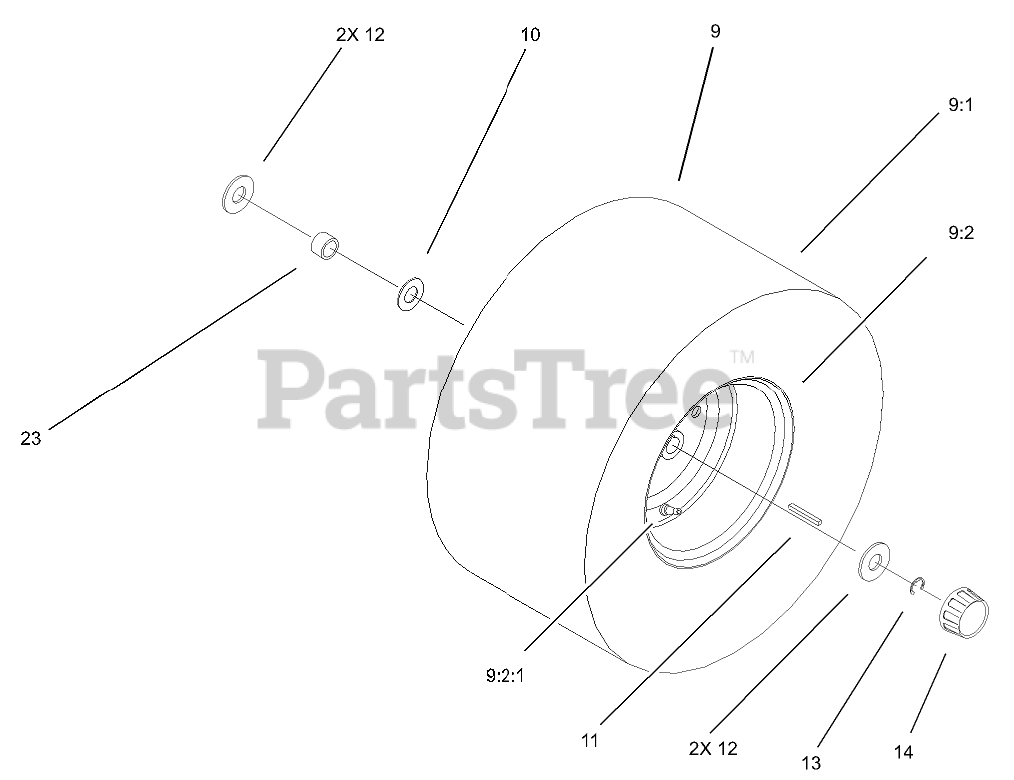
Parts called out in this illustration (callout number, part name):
9	REAR WHEEL & TIRE ASM
9:1	TIRE
9:2:1	STEM-VALVE
10	WASHER-THRUST
11	KEY-SQUARE
12	WASHER-PLAIN
13	E-RING
14	CAP-HUB
23	SPACER-WHEEL
